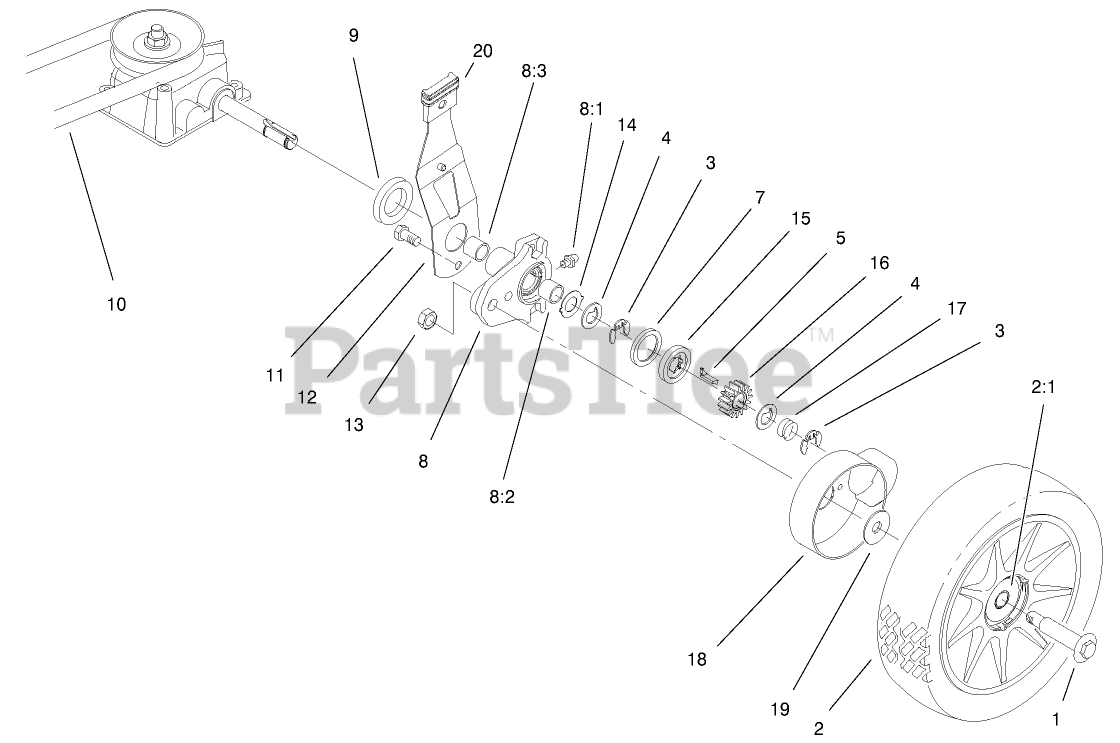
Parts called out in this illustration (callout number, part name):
1	BOLT-SHOULDER
2	WHEEL AND TIRE ASM
2:1	BUSHING
3	RING-RETAINING,CLIP
4	WASHER-THRUST, KEYED
5	KEY-ROCKING, LH
7	RING-FRICTION
8	REAR HEIGHT ADJUSTMENT ARM ASM
8:1	FITTING-GREASE
8:2	BUSHING
8:3	BUSHING
9	SPACER-SHAFT, AXLE
10	V-BELT
11	SCREW-HWH
12	REAR SPRING ARM ASM
13	NUT-JAM, LOCKING
14	WASHER-ARM, PIVOT
15	WASHER-CLUTCH
16	GEAR-PINION
17	SPRING-COMPRESSION
18	COVER-WHEEL
19	WASHER-STEPPED
20	KNOB-LEVER, HEIGHT ADJUSTMENT
